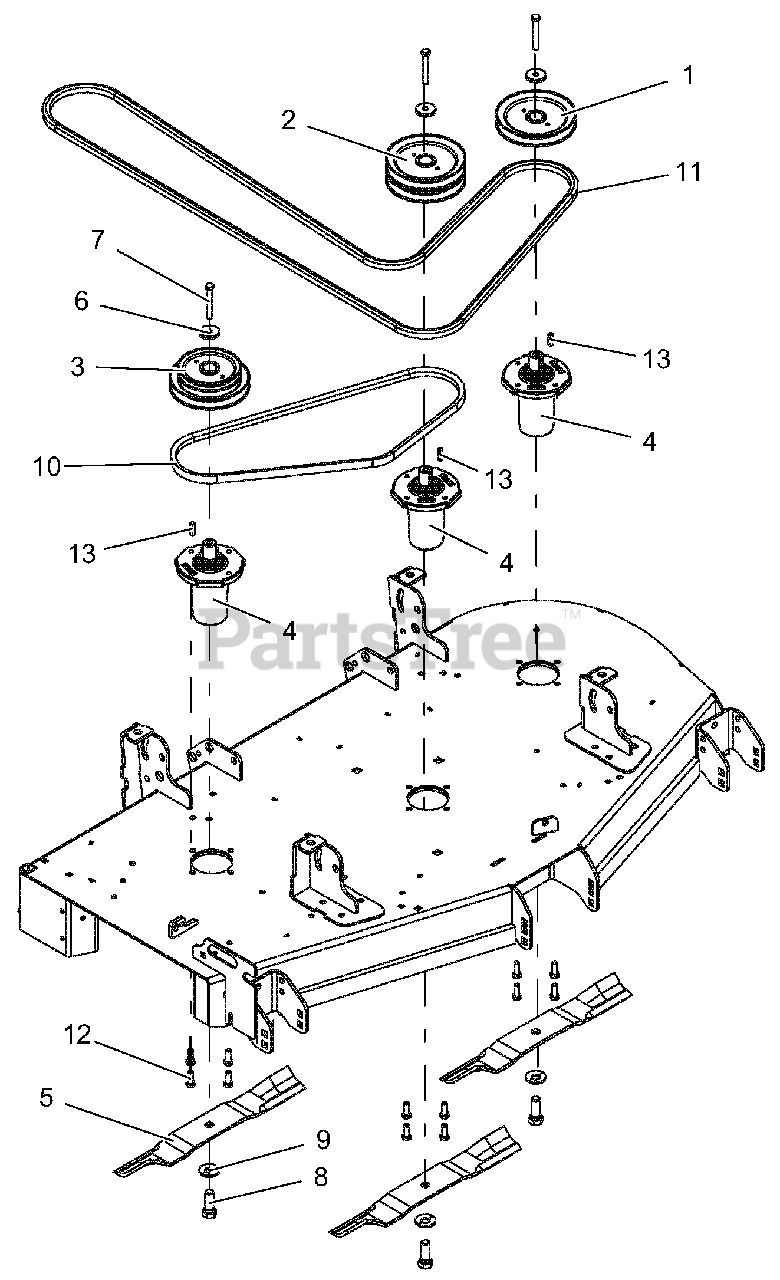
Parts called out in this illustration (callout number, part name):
1	PULLEY, SINGLE -1" ID X 6.00" OD-BLACK
2	PULLEY, DOUBLE -1" ID X 6.00" OD-BLACK
3	PULLEY, DOUBLE -1" ID X 6.00" & 4.75" OD
4	SERVICE, ASM SPINDLE- DUCTILE
5	BLADE, 18.00" MOVER (HI-LIFT)
6	RETAINER, SHEAVE SPINDLE
7	BLT-HEX .38-16X2.75 GR8 YWZC
8	BLT, HEX .62-18X1.75 GR8 YWZC
9	WSHR, BLVL .63X1.625X.14
10	BELT, B 56.00 RAW COGGED
11	BELT, BB 118.00 WRAPPED HEX
12	BLT-HEX .38-16X1.00 GR5 YWZC EP30
13	KEY-SQ .250X.250X1.00 RC 40-50
